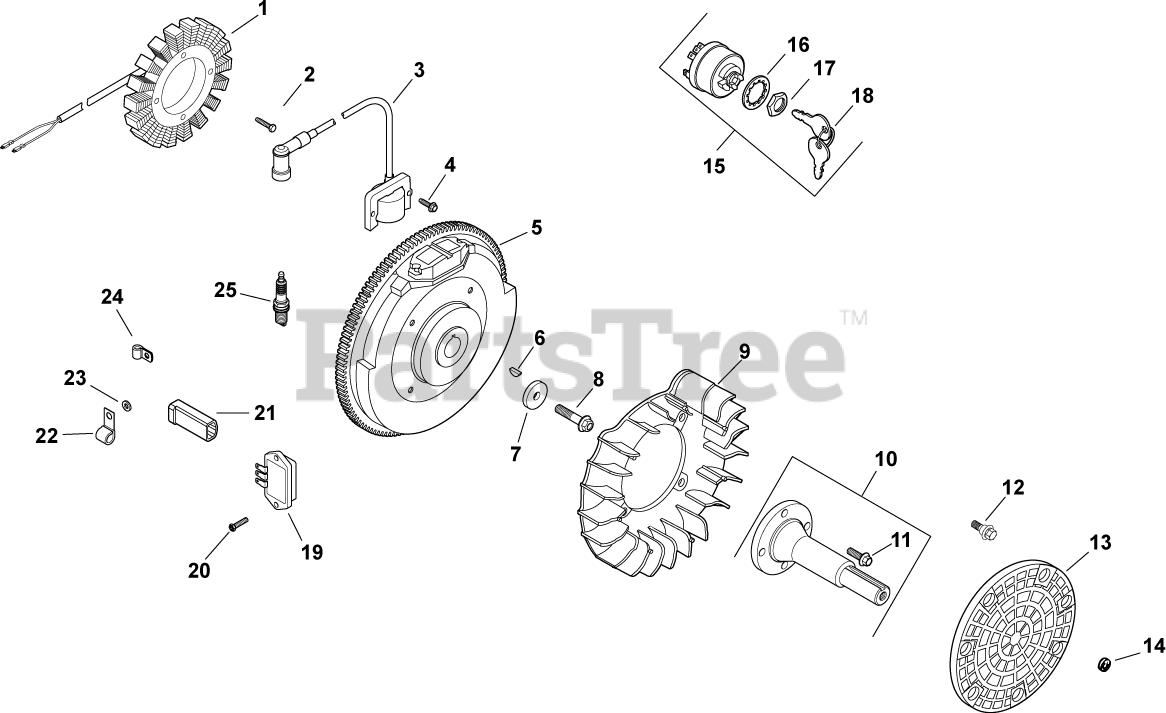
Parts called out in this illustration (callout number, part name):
1	KIT, 15 / 20 AMP STATOR
2	SCREW, M5X0.8X25 - (#25086402S)
3	KIT, MODULE IGNTN (CDI FIXED)
4	SCREW, FLG THD FRM M5X.8X20-(#25086399S)
6	KEY, 3/16" X 5/8"
7	WASHER, FLAT 13/32"
8	SCREW, FLG M10X1.5X45 - (#25086361S)
9	FAN - USE (#24 157 11-S)
10	SHAFT, FRONT DRIVE
11	SCREW, FLG M8X1.25X25
12	BOLT, SHOULDER
13	SCREEN, GRASS-USE 24 755 171-S
15	SWITCH ASSY, KEY (KM)-USE 25 099 32-S
16	WASHER, INTERNAL TOOTH
17	NUT, KEY SWITCH
18	KEY, SET -USE 48 340 01-S
19	REG/RECT-15 AMP (KM)-USE 41 403 10-S
20	SCREW, HEX FLANGE HI-LO
21	CONNECTOR (1 CONTACT)
22	CLIP, CABLE
23	WASHER, FLAT 1/4" (O.D. 1/2")
24	CLIP, TUBE & WIRING (KM)
25	PLUG, SPARK (STD)
